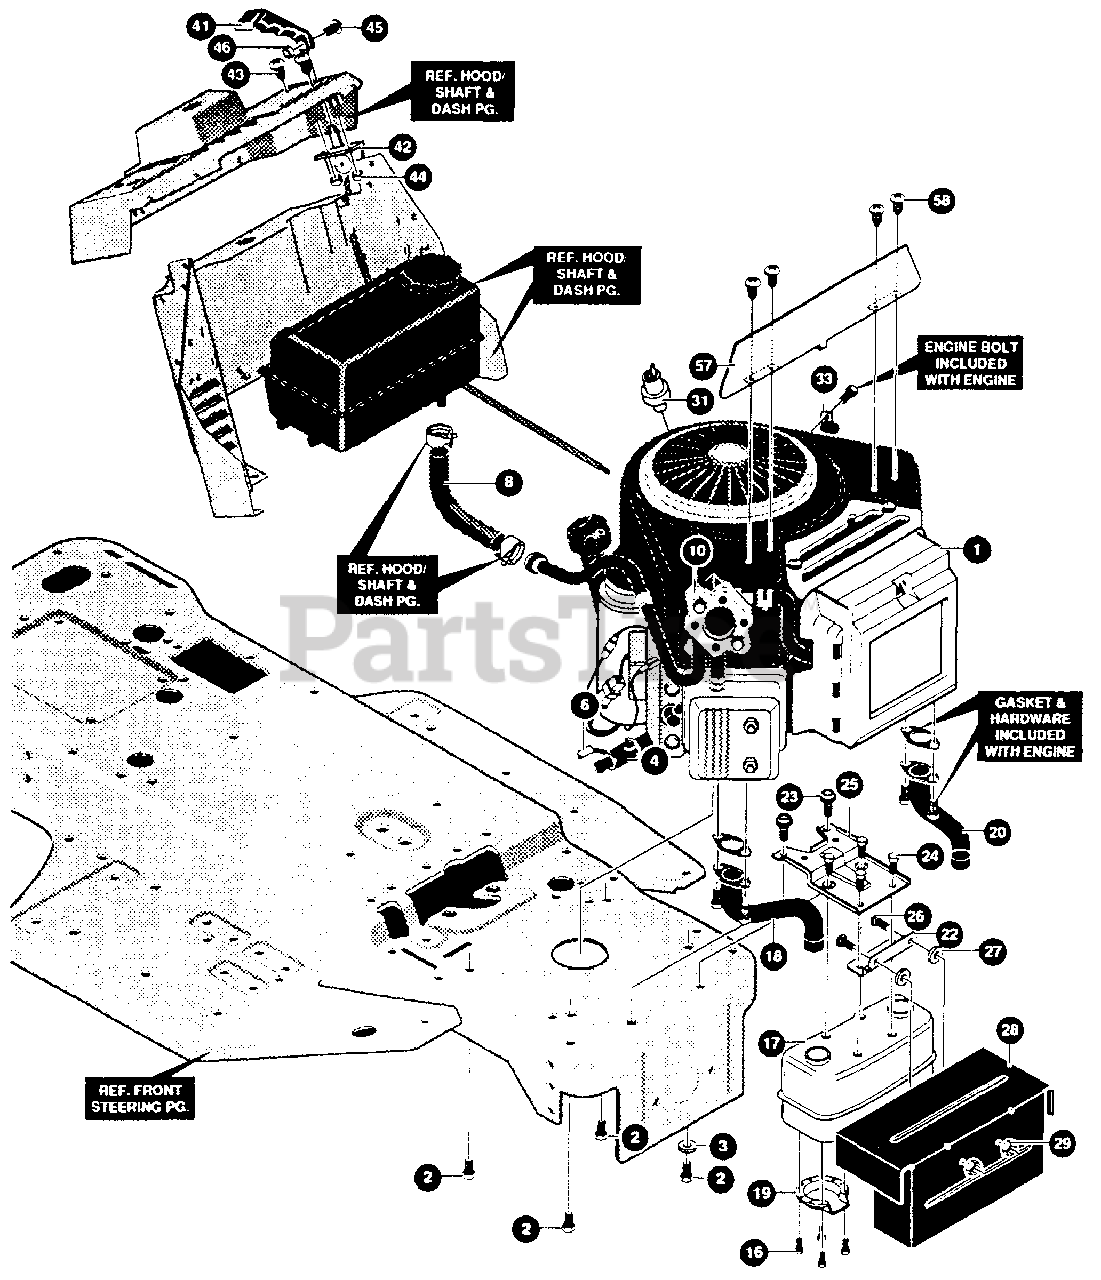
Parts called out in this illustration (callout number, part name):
1	14-16HP VANGUARD
2	SCREW, 3/8-16X1.25 WAHHTAPBLKP
3	WASHER, EXLK .384X.69X.04
4	NIPPLE 3/8-18 NPT X 4"
6	CAP, PIPE 3/8-18
8	TUBING,.25X.50X BULK GAS LINE
10	REGULATOR,VOLTAGE W/O SENSOR
16	SCREW, #8-32X .38 HHWATAP
17	MUFFLER 14/18 TWIN NLSN 22785C
18	EXHAUST TUBE 15HP RH B&S VANG
19	DEFLECTOR SIDE OUT
20	EXHAUST TUBE 15HP LH B&S VANG
22	BRACKET, TRANSAXLE
23	SCREW, 5/16-18X .50 WAHHTAP
24	SCREW, 1/4-20X .75 WAHHTAP
25	BRACKET, MUFFLER
26	BOLT. 5/16-18X 5/16-18X.63 CARR
27	PUSHNUT, 5/16 BOLT RETAINER
28	SHIELD, MUFFLER HEAT TWIN
29	NUT, 5/16-18 HXWDFLLK
31	OIL SENSOR, B&S TWIN CYL
33	RETAINER,.31IDX.62X.03 WIRE
41	KNOB, THROTTLE CONTROL
42	THROTTLE CONTROL
43	SCREW, 10-24X.63PHPNMA
44	NUT, #10-24 HXHDNYLK
45	SCREW, #8-32X .38 PHPNMA
46	NUT, #8-32 REGHEX
57	HEAT SHIELD V/G
58	SCREW, 10-16X 50 DRILLTITE
